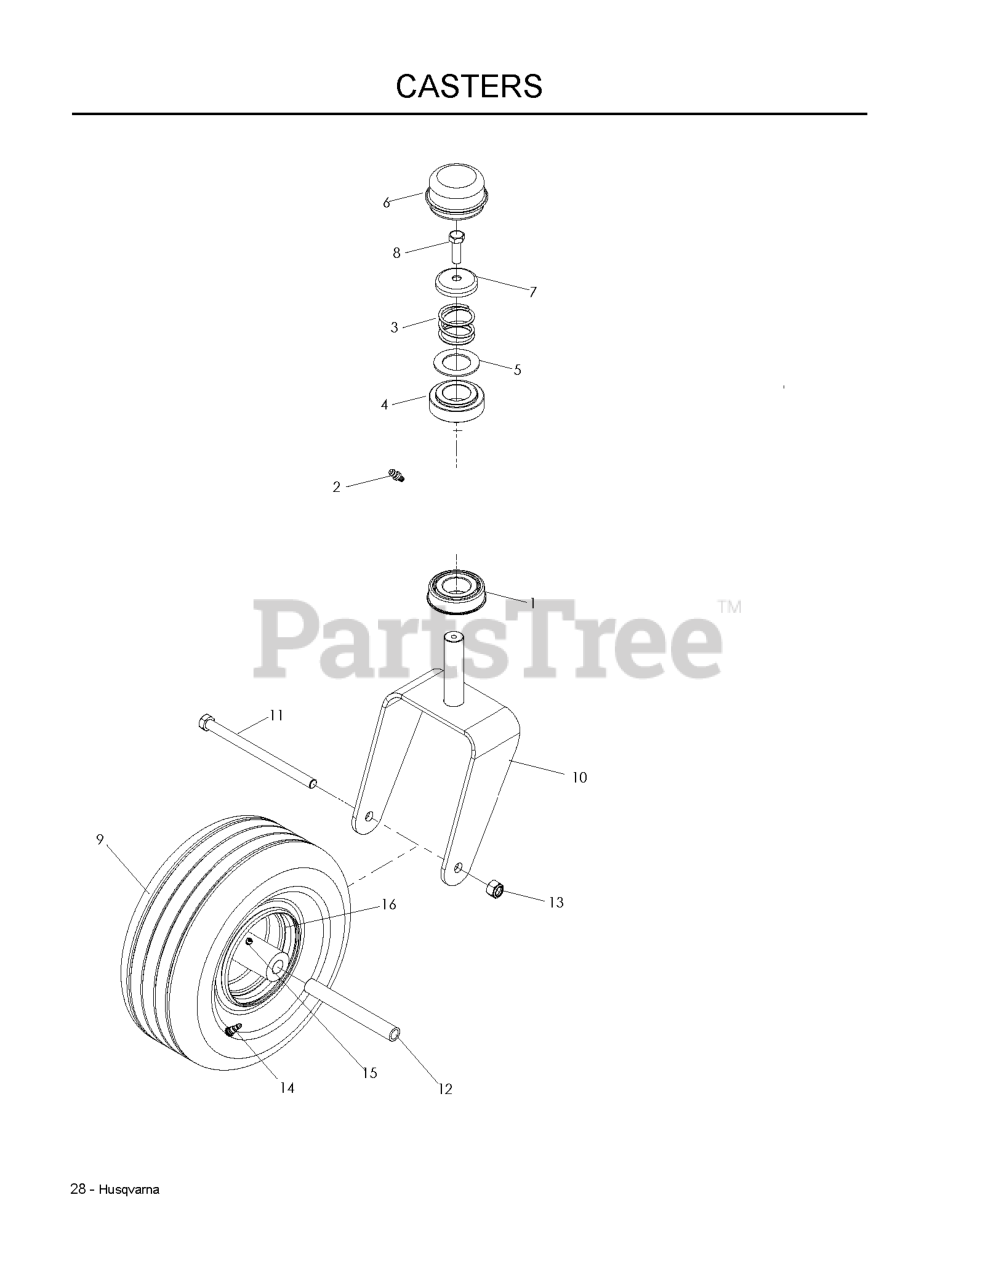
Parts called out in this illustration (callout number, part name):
1	BEARING FLANGED
2	ZERK, 3/16, DRIVE IN
3	SPRING, CASTER
4	BUSHING, CASTER
5	WASHER, 1.025 ID X 1.64
6	GREASE CAP
7	CASTER.PLUG
8	HCS 5/16C X 1
9	TIRE.ASSEM.13X5-6.SMOOTH.SILVE
10	YOKE, CASTER
11	SCREW 1/2C X 7 1/2 HEX CAP
12	SPACER, CASTER
13	NUT 1/2-13 HEX NYLOC ZD
14	VALVE STEM TR-412
15	ZERK 1/8 NPT
16	RIM
